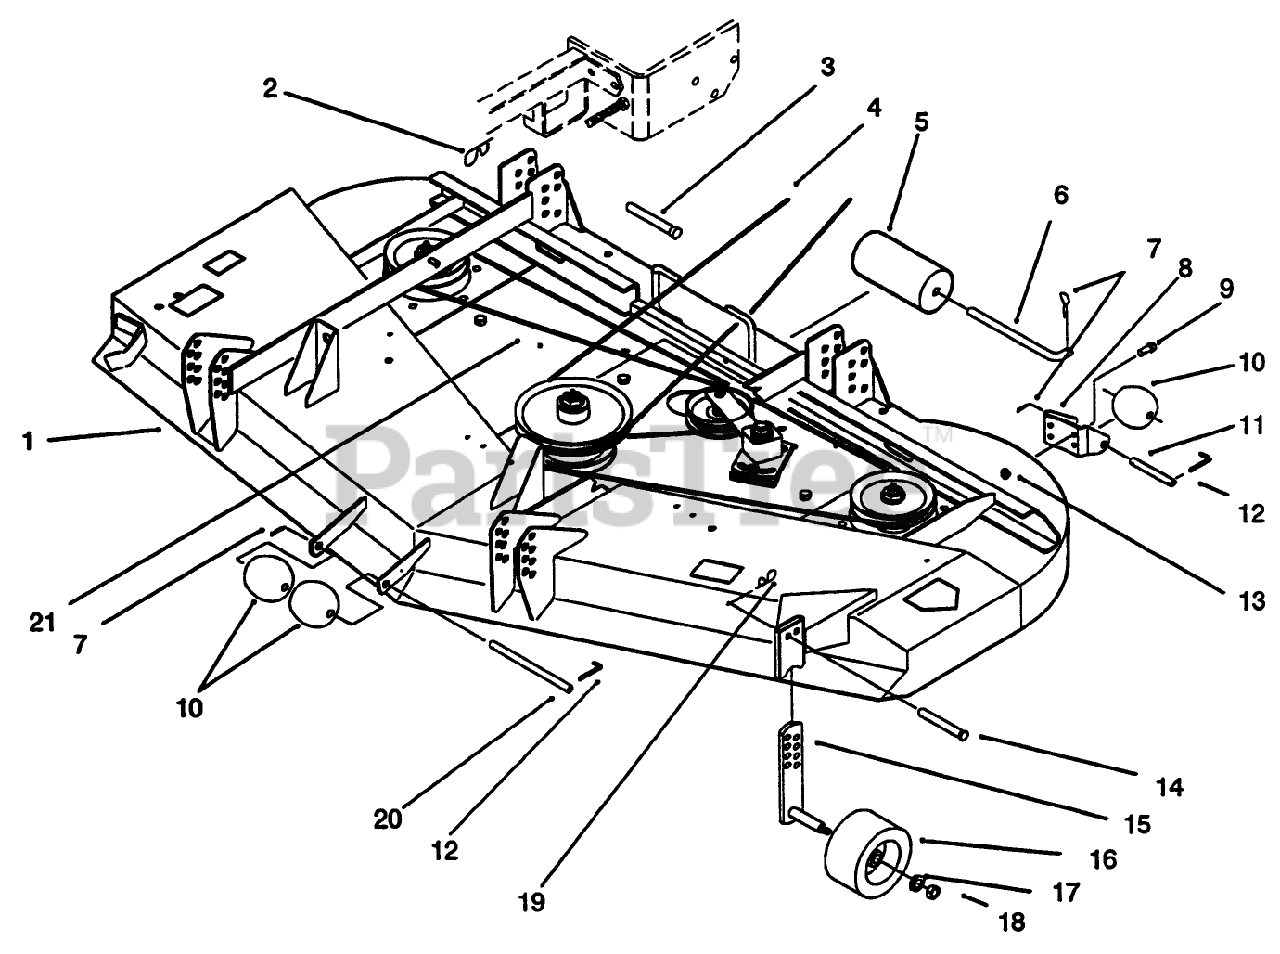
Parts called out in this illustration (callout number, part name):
1	Deck Assembly (Incl. Decals on page 2)
2	PIN-HAIR
3	PIN-CLEVIS
4	V-BELT, DECK DRIVE
5	ROLLER-DECK
6	SHAFT-ROLLER, REAR
7	PIN-COTTER
8	Bracket-Roller
9	SCREW-HH
10	ROLLER
11	SHAFT-ROLLER
12	PIN-SPECIAL
13	NUT-HHF, WHIZ
14	PIN-CLEVIS
15	GAGE-WHEEL
16	WHEEL-GAGE
17	WASHER-FLAT
18	NUT-LOCK, NI
19	PIN-HAIR
20	SHAFT-ROLLER
21	V-BELT
